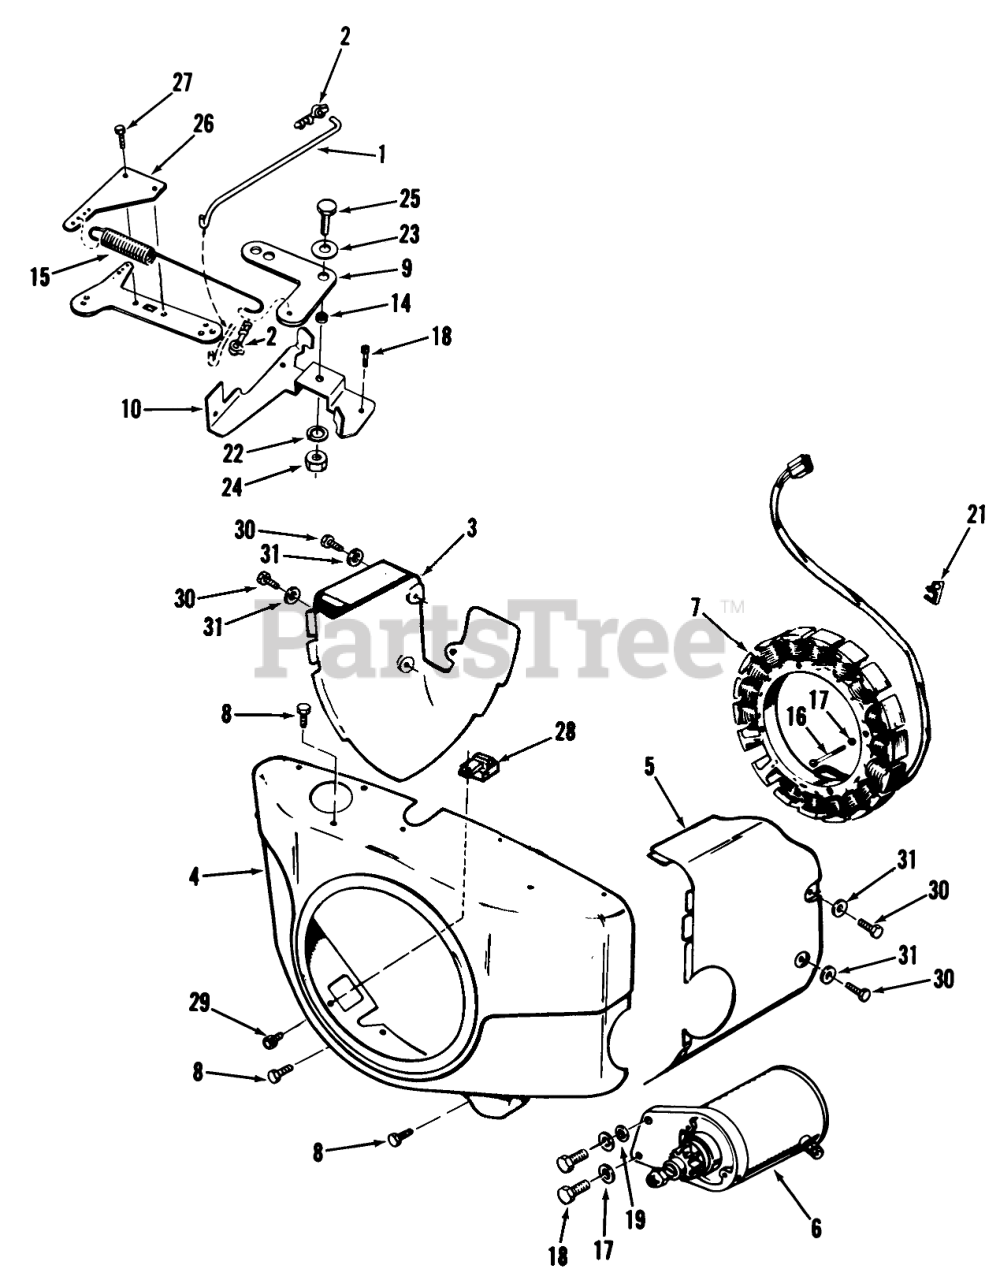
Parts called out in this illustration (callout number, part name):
18	HEX HD CAP SCREW
26	ADAPTOR-GOV ARM
27	Screw 10-32 X 1/2
